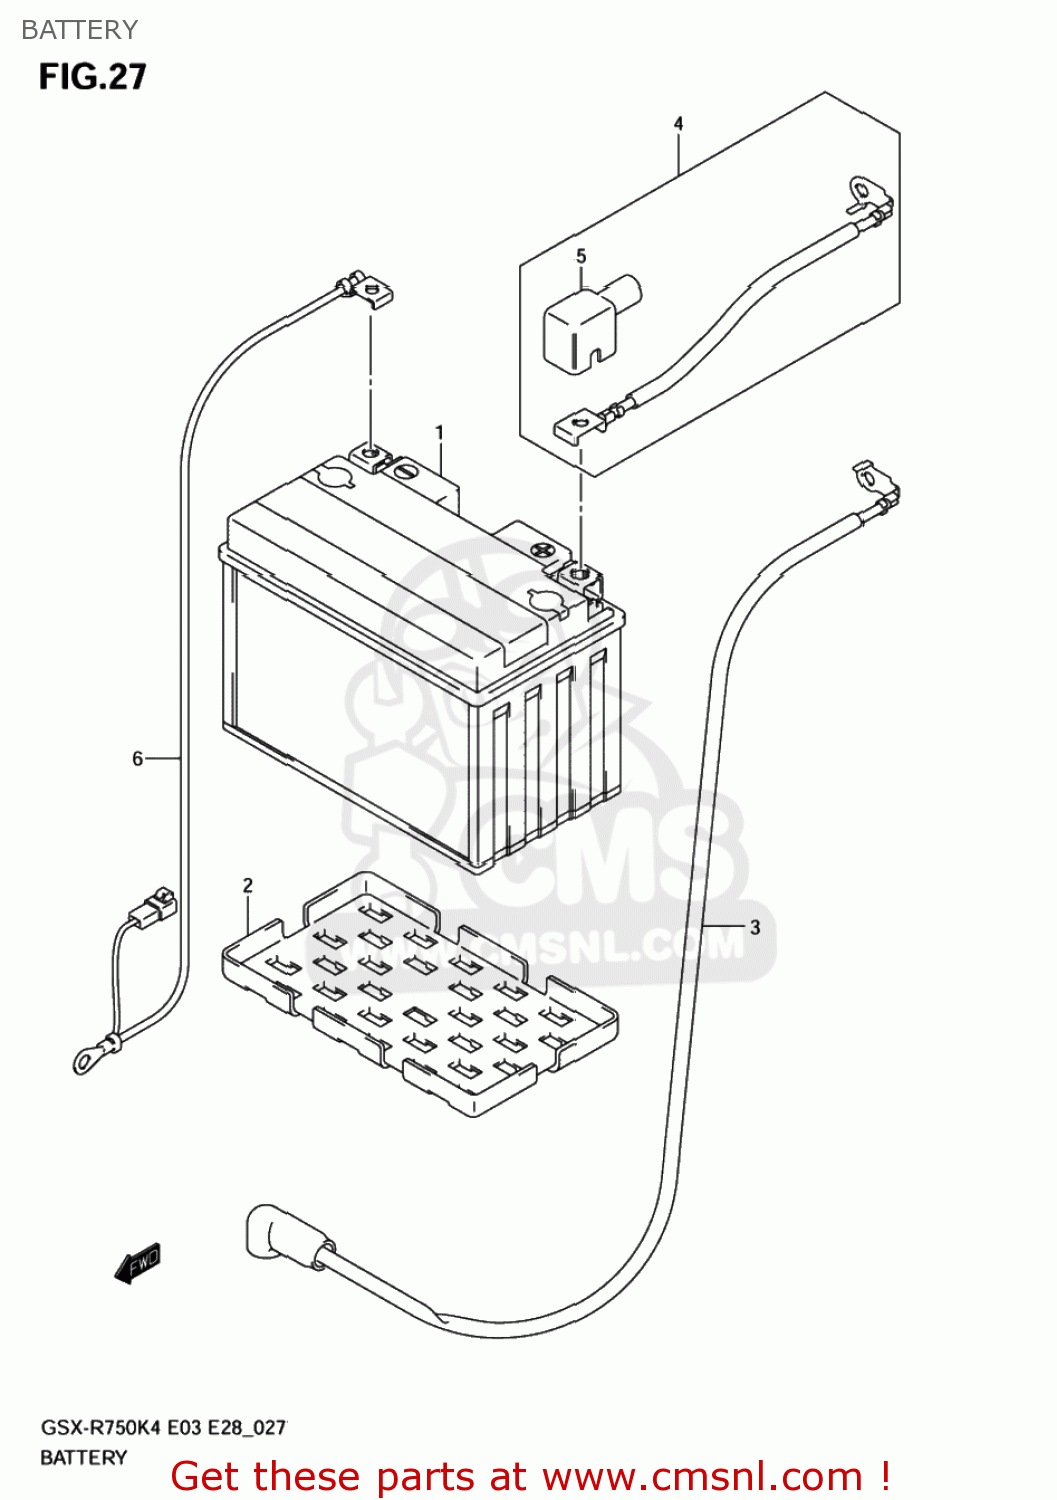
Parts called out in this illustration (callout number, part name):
1	BATTERY(YT12A-BS,12V10.5AH)
2	PROTECTOR,BATTERY
3	WIRE,STARTER MOTOR LEAD
4	WIRE,BATTERY PLUS LEAD
5	CAP,BATTERY PLUS
6	WIRE,BATTERY MINUS LEAD
